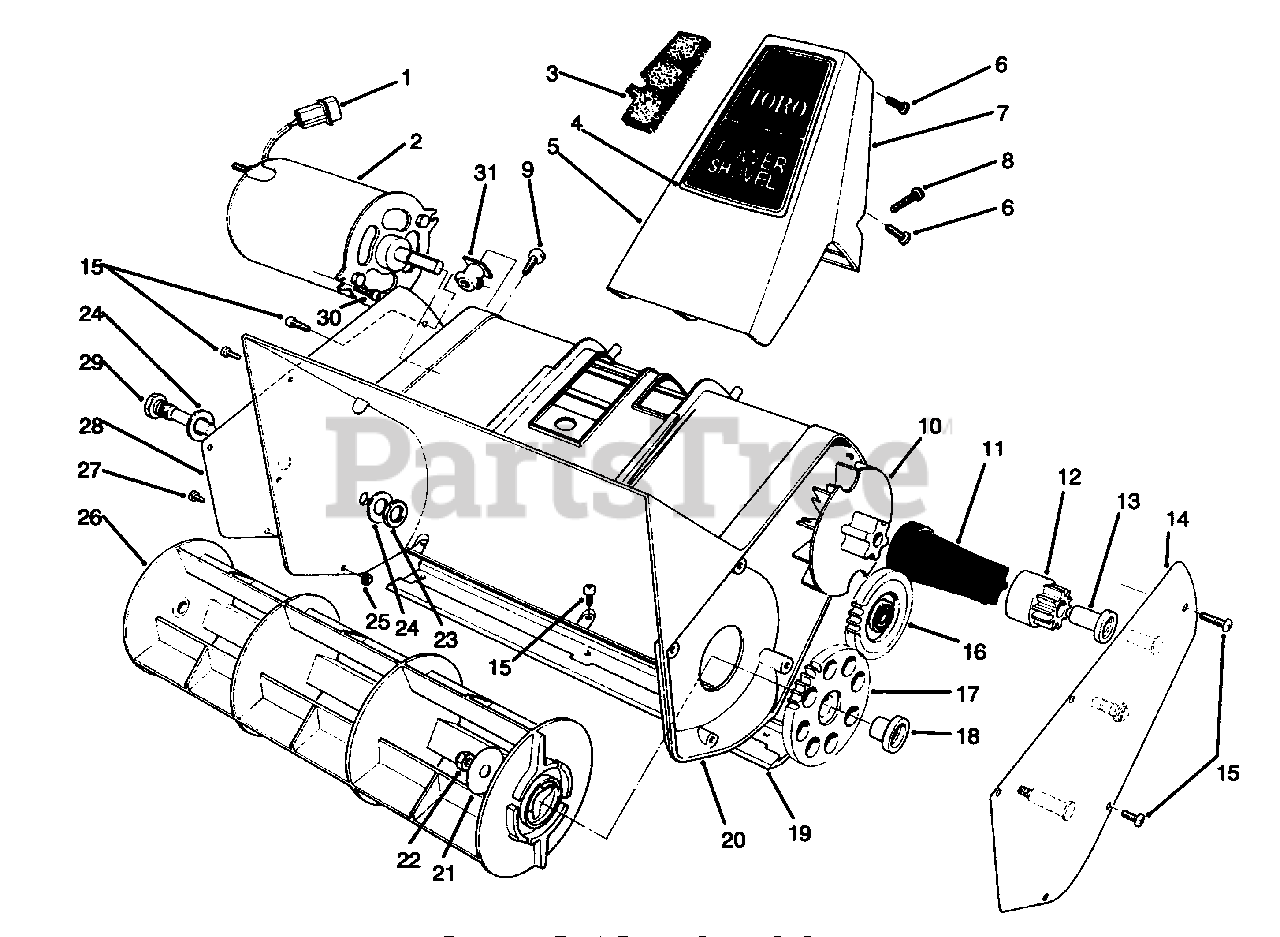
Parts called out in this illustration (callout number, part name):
1	Housing-Pin
2	Motor-(Incl. Ref. #1)
3	Filter-Foam
4	Decal-Handle Support
5	Handle Support-Front
6	Screw-Pan Head
7	Handle Support-Back
8	Screw-Pan Hd.
9	Screw-Phillips Head
11	Coupling-Drive
12	Drive Gear (Incl. Ref. #13)
13	Bushing-Drive Gear
14	Gear-Carrier
15	Screw-Pan Head
16	Idler Gear Assembly
17	Rotor Gear Assembly (Incl. ref. #18)
18	Bushing-Rotor
20	Housing
21	Washer-Rotor
22	Nut-Lock
23	Nut-Lock
24	Washer-Flat
25	Nut-Lock, Thin
27	Screw-Pan Head
28	Cover-Right Side
29	Pin-Rotor
30	Screw-Pan Head
31	Block-Mounting
